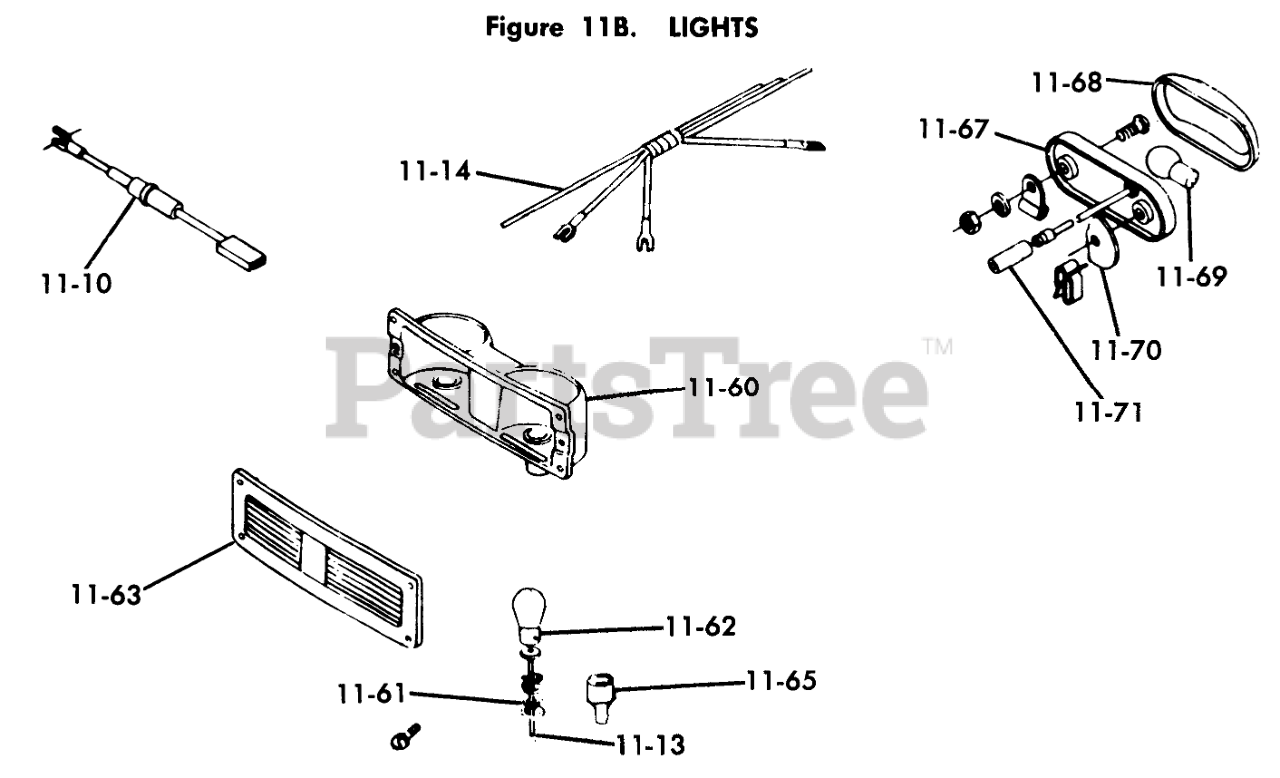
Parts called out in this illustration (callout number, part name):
11-60	ASSY REFLECTOR HOUSI
11-61	SPRING
11-62	BULB
11-63	Lens
11-63	Pan HD Swage
11-65	CONNECTOR 3 WIRE
11-65	SPEED CLIP
11-67	Base
11-68	Lens
11-69	Bulb
11-70	Mounting Pad
11-71	CONNECTOR 2 WIRE
11-71	SPEED CLIP
11-71	Screw
11-71	Nut
11-71	Lockwasher
